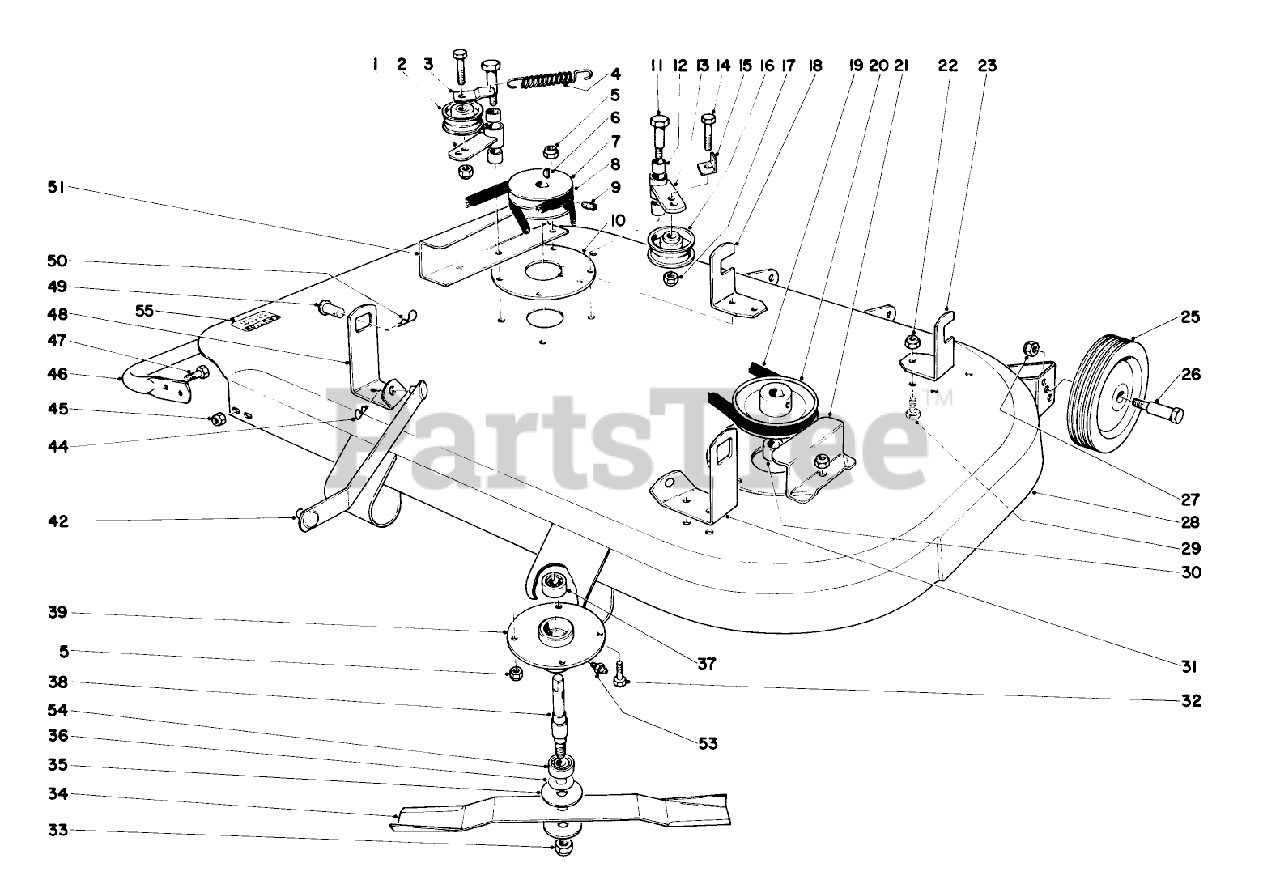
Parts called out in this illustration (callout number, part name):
1	Idler Plate (Incl. Ref. #12)
6	KEY-WOODRUFF
9	SCREW-SET, HSH
12	Bushing
14	SCREW-HH
18	Bracket
21	Belt Guard
23	Bracket Mower
29	SCREW-HH
32	SCREW-HH
34	Blade
35	WASHER
36	WASHER
44	PIN-COTTER
47	SCREW-CARR
50	PIN-COTTER
53	FITTING-GREASE
55	Decal
